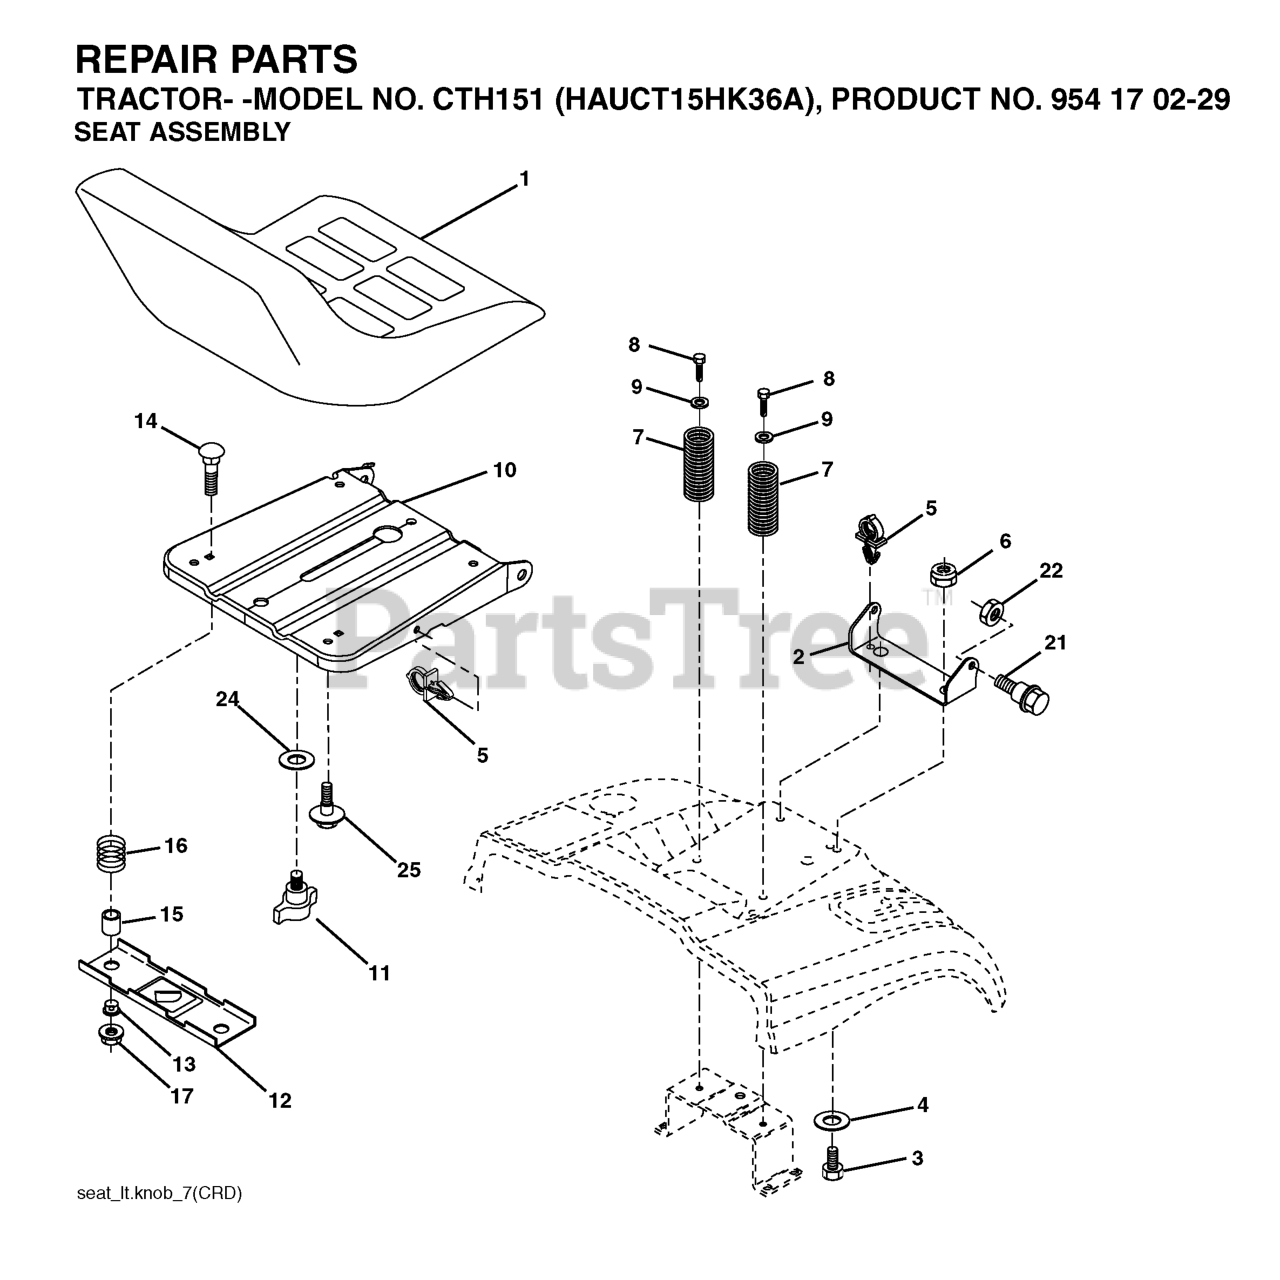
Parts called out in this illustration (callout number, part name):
1	SEAT
2	SEAT PIVOT BRKT
3	BOLT, HEX 3/8-16X1
6	NUT
7	SPRING COMPRESSION
8	SCREW 3/8-16X1
9	WASHER
10	PAN SEAT
11	KNOB.SEAT.ADJ.WINGNUT
12	BRKT SWITCH
14	BOLT.ROUND.HEAD.SQUARE.NECK
15	SPACER SPLIT 28X.96
17	NUT T
21	BOLT.SHOULDER.5/16-18
22	NUT.71038.31-18.HEX.NYLOCK
25	BOLT,SHOULD
